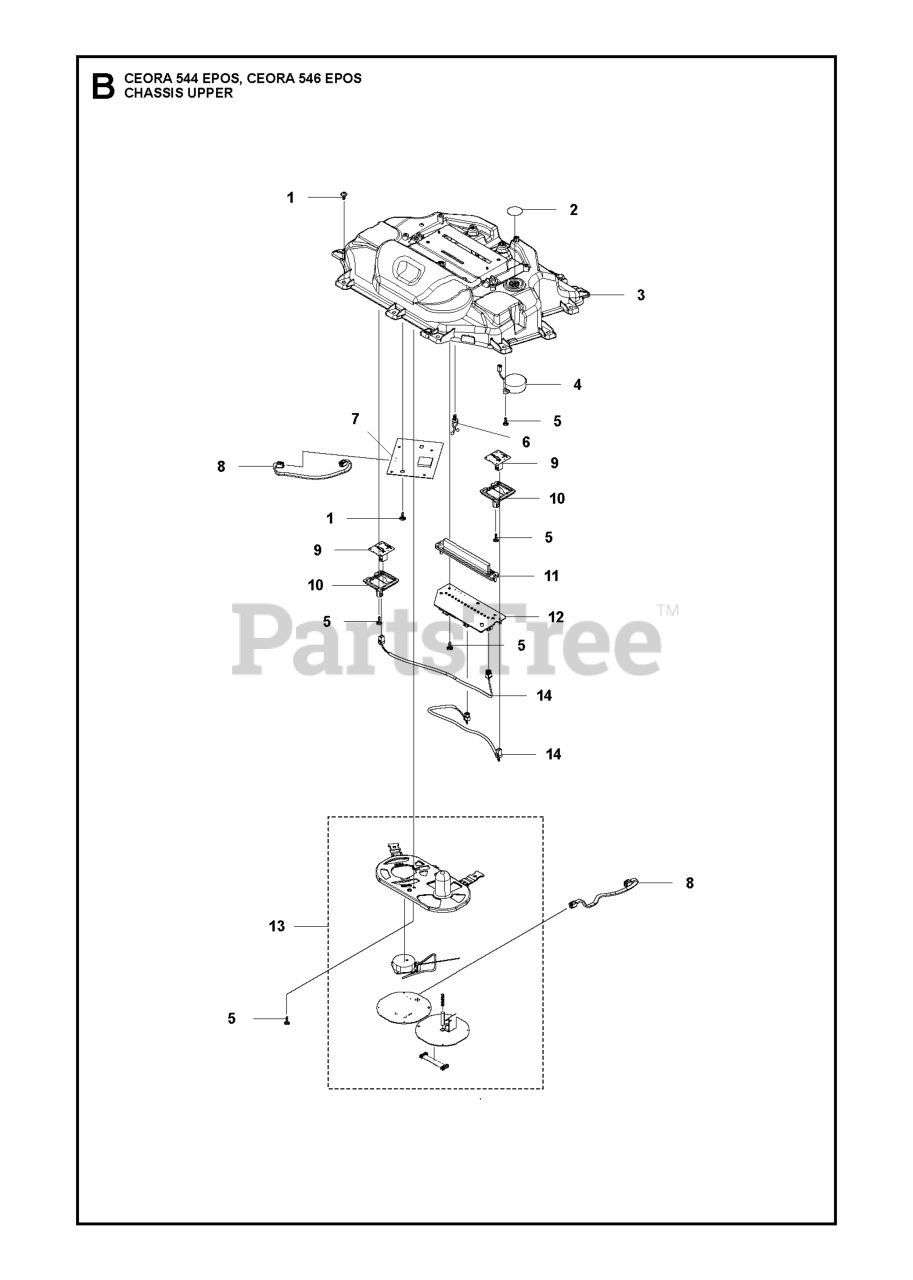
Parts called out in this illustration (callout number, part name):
1	SCREW ITXPANT
2	KIT AIR FILTER KIT 305 - 10 PC
3	CHASSIS UPPER - DRIVE UNIT
4	BUZZER BUZZER 2.8KHZ 60X16MM H
5	SCREW 14MM
6	HOLDER TWIST LOCK
8	Wires
9	PRINTED CIRCUIT ASSY PCBA MAGN
10	Holders
11	GUIDE LIGHT GUIDE DRIVE UNIT T
12	PRINTED CIRCUIT ASSY HMI BOARD
13	HOLDER ASSY ANTENNA MODULE 915
14	WIRING ASSY MAGNETIC & LOOP SE
